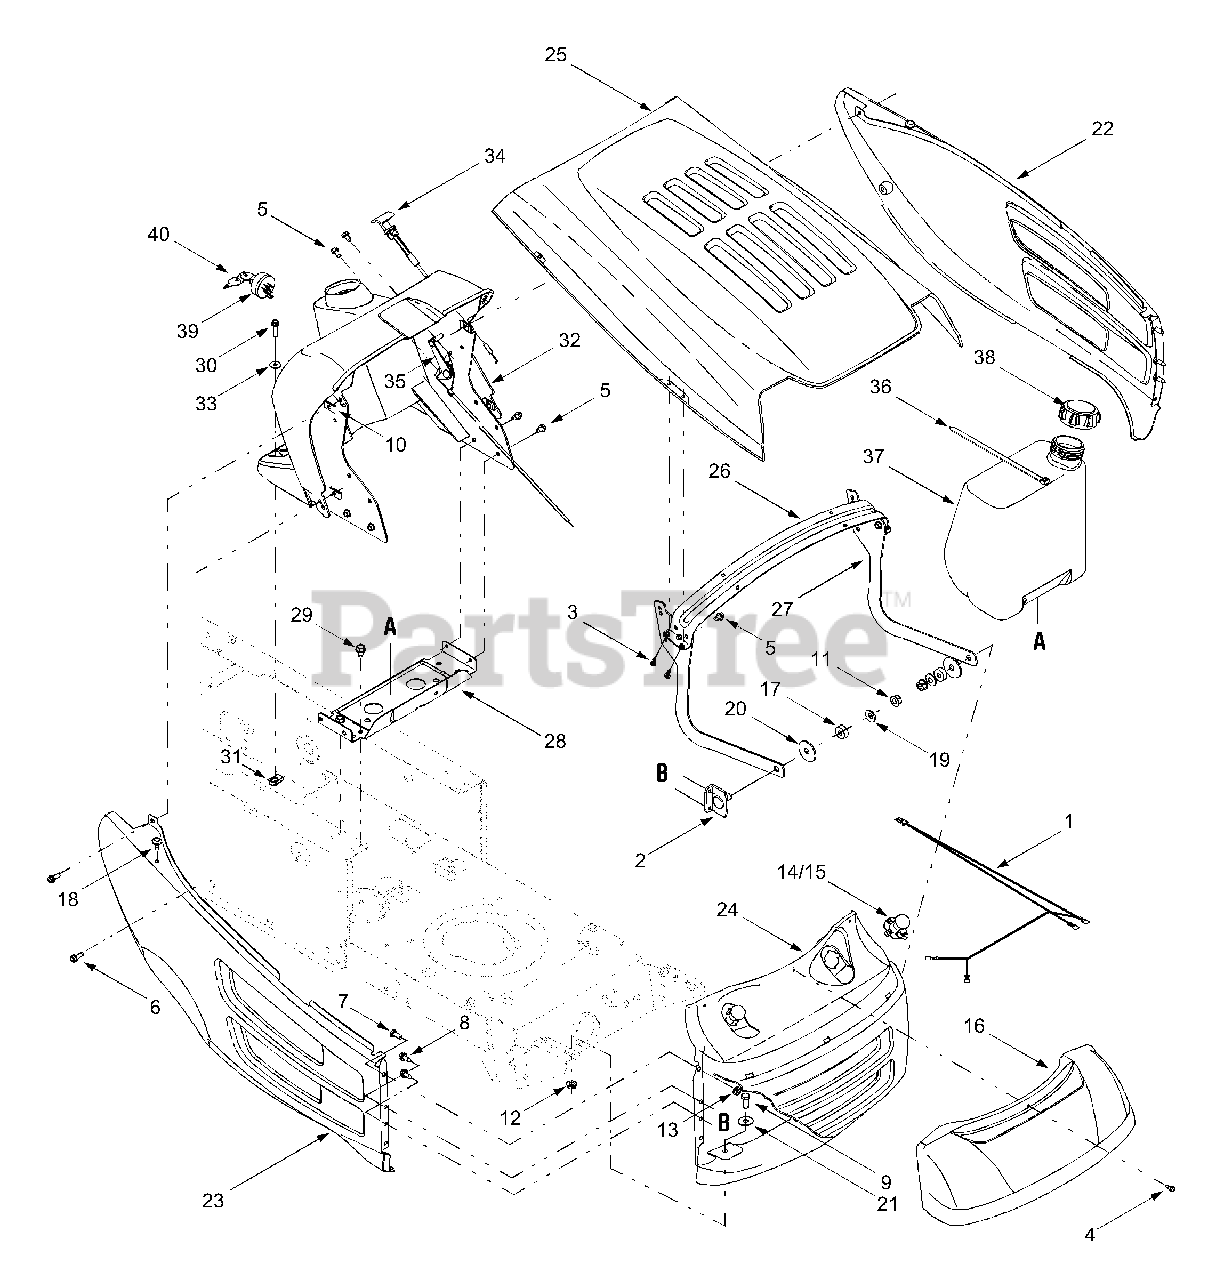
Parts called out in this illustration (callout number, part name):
1	Headlamp Harness Assembly
3	Screw, #10-16 x .50
4	Screw, #10-16 x .50
5	Self-tapping Screw, 1/4-20 x .5
6	Self-tapping Screw, 1/4-20 x .75
7	Hex Cap Screw:1/4-20 x .620
8	Hex Index Washer Screw, 1/4-14 x .0625
9	Hex Screw, 5/16-18 x .75
10	U-type Speed Nut, 1/4-20
11	Flange Lock Nut, 3/8-16
12	Flange Lock Nut, 5/16-18
13	Flange Lock Nut, 1/4-20
14	Headlamp, 12V
15	Headlamp Socket
16	Headlight Lens (8-style)
17	Rubber Washer, .87 x .33
18	Rubber Bumper
19	Flat Washer, .406 x .875 x .059
20	Flat Washer, .406 x 1.5 x 11 gauge
21	Flat Washer, .344 x 1.0 x .063
29	Self-tapping Screw, 5/16-18 x .5
30	Self-tapping Screw, 1/4-20 x 1.0
31	U-type Speed Nut, 1/4-20
32	Dash Panel (models w/o choke knob)
33	Flat Washer, .260 x .720 x .060
34	Choke Control, 38"
35	Throttle / Choke Control, 18.5"
36	Cable Tie, 30.66
37	Fuel Tank, 1.5 gal.
38	Fuel Tank Cap
39	Ignition Switch, 6-pin
40	Keys (pair)
